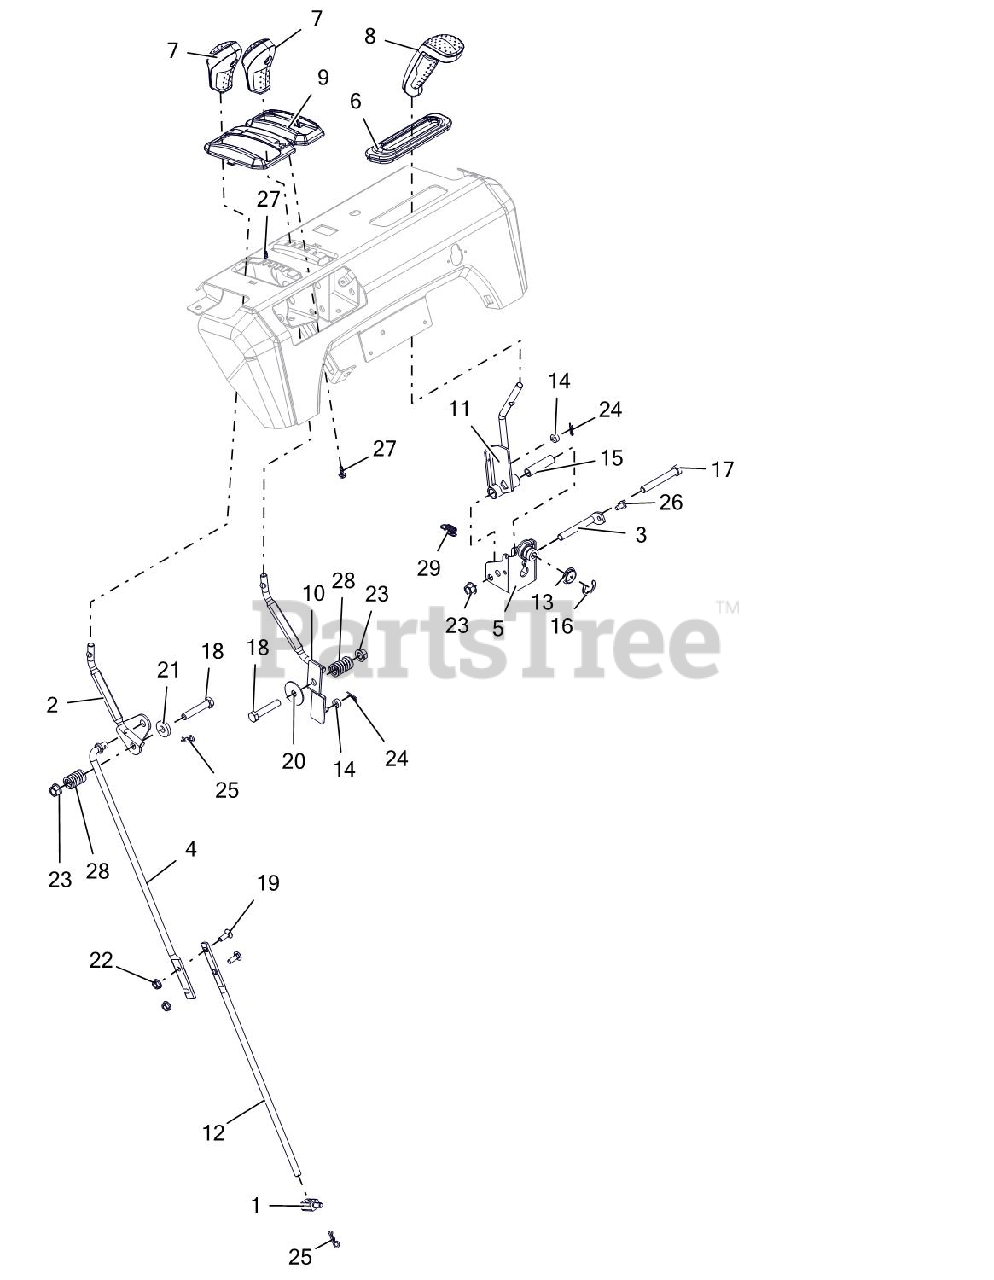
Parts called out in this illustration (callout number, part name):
1	PIVOT,SHIFT ROD .375-16(TRUNN)
2	WELDMENT,LG DASH SPEED CONTROL
3	ROD, PIVOT - INTERLOCK
4	ROD, SHIFT - UPPER
5	WELDMENT-CONTROL BRACKET-CHUTE
6	GROMMET, BOOT, QUICK TURN
7	KNOB, CONTROL, DASH
8	HANDLE, QUICK TURN, ASM
9	BEZEL, SHIFT - FRICTION SNOW
10	WELDMENT,LG DASH DEFL CONTROL
11	WELDMENT,LG DASH QT CONTROL
12	ROD, SHIFT-LOWER (LG DASH DLX)
13	BUSHING, POLYLINER-.75 SNAPIN
14	BSHG-SLV .265X.500X.219
15	SPCR, WHEEL .385X.500X2.00
16	E-RING .750X.050
17	@BLT-HEX .38-16X2.75 GR5 YWZC
18	@BLT-HEX .38-16X2.00 GR5 YWZC
19	@BLT-RDHDSQNK .25-20X.75 G5YZ
20	WSHR-FL-STL .380X1.50X.062 YWZ
21	WSHR-FL-STL .406X1.00X.188 YWZ
22	@NUT-LK-CTR-FLG .25-20 YWZC
23	@NUT-LK-TOP-FLG .38-16 YWZC
24	PIN-HAIR INT .06X.18X.77
25	PIN-HAIR INT .08X.18X1.18 YWZC
26	SCR-TAP .25-20X.50 HWH TR YWZ
27	SCR-TAP #10X.50 BOSS INDHXHD
28	SG-COMP .125X.781X1.250
29	SPRING-EXT .047X.438X1.45
